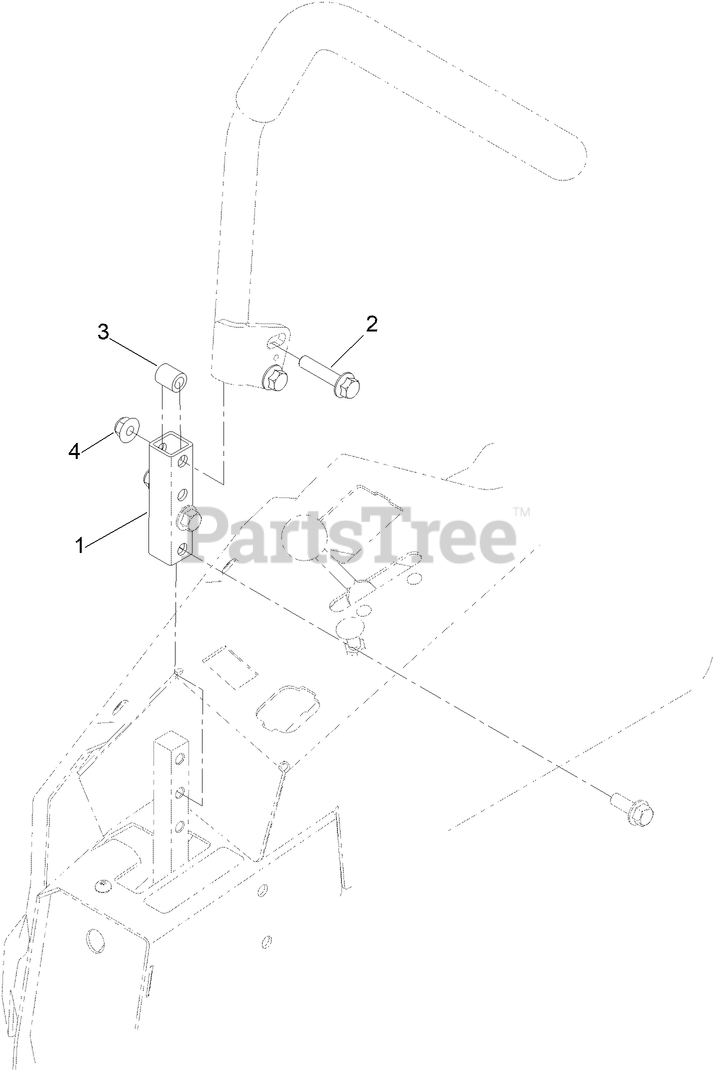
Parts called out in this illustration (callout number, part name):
1	TUBE-EXTENSION
2	SCREW-HHF
3	SPACER-WHEEL
4	NUT-HF, NI
